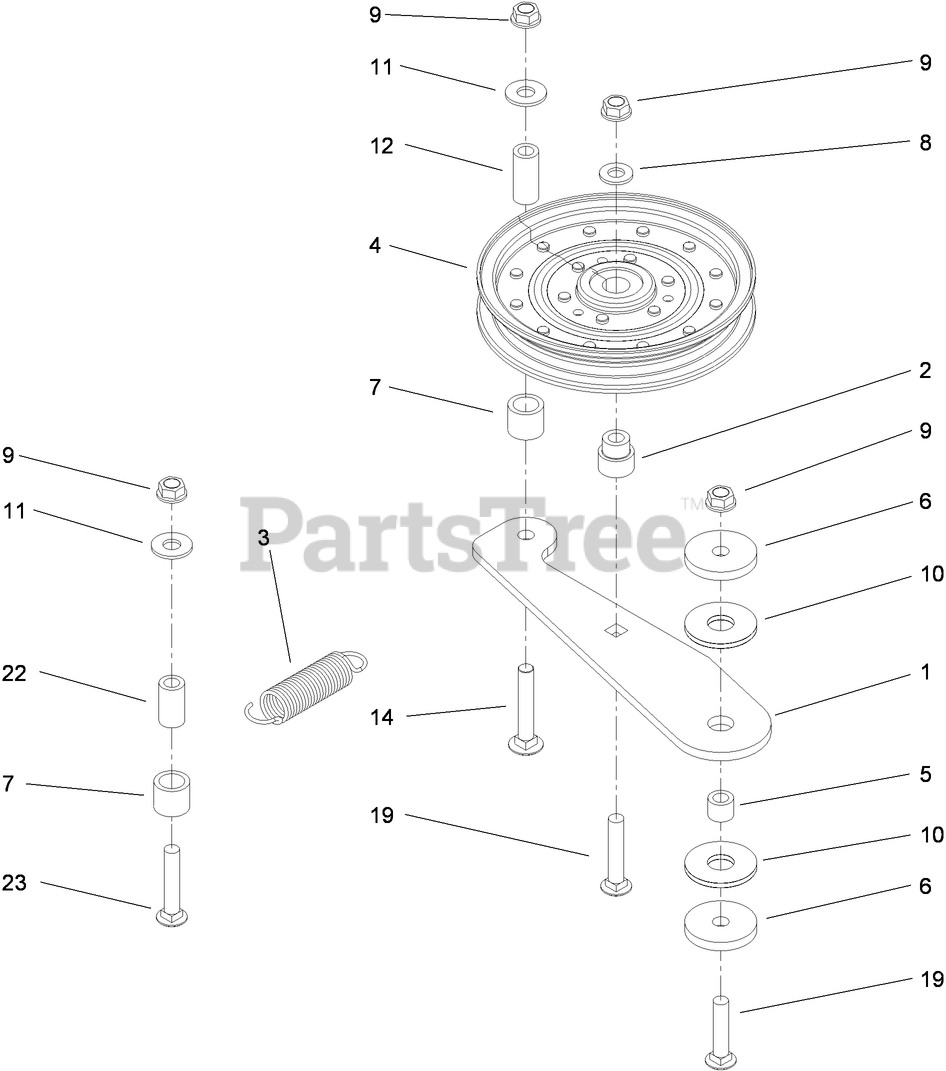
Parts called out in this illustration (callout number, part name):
1	ARM-IDLER
2	BUSHING-IDLER
3	SPRING-EXTENSION
4	IDLER-PULLEY, FLAT
5	BUSHING-LEVER, LIFT
6	WASHER-PLAIN
7	SPACER-RUBBER
8	WASHER-FLAT
9	NUT-HF, NI
10	WASHER-FRICTION, COMPOSITE
11	WASHER-FLAT
12	SPACER
14	SCREW-CARR
19	SCREW-CARR
22	SPACER
23	BOLT-CARR, SHORT NECK
